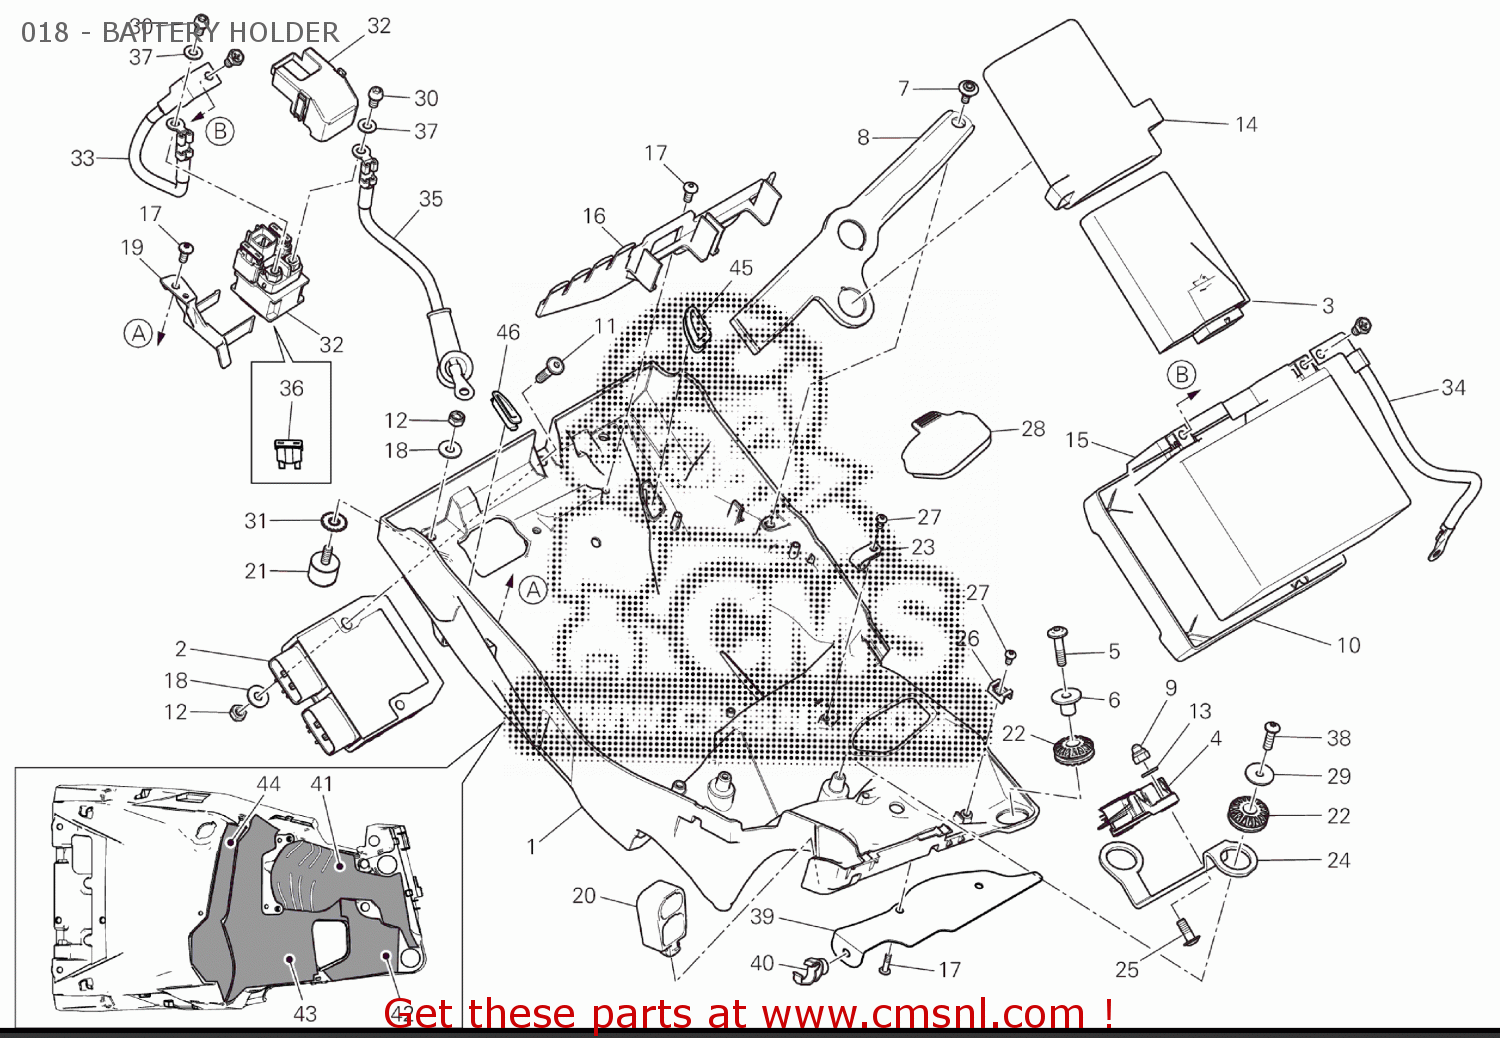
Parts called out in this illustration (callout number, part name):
1	BATTERY HOLDER
2	VOLTAGE REGULATOR
3	BLACKBOX UNIT
4	PIATTAFORMA INERZIALE
5	SCREW
6	SPACER
7	SCREW TCEI M5X9
8	BRACKET, BATTERY BAND
9	NUT, SELF-LOCKING M6
10	BATTERY CARPET
11	SCREW TBEIF M6X25
12	NUT
13	WASHER 6.4X12.5X1.6
14	BRACKET
15	BATTERY
16	BRACKET, FUSE BOX
17	SCREW
18	WASHER 6.4X16X1.5
19	BRACKET, RELAY
20	BRACKET, CONNECTOR
21	VIBRATION DAMPER
22	VIBRATION DAMPER PAD
23	FAIRLEAD
24	BRACKET
25	SCREW
26	HOSE GUIDE
27	SCREW, TAPPING 4X8 WN1412
28	GUARD
29	WASHER 5.3X15X1
30	SCREW TCEIF M6X10
31	TOOTHED LOCK WASHER
32	STARTER RELAY
33	BATTERY - SOLENOID STARTER CABLE
34	BATTERY - ENGINE GROUNDING CABLE
35	SOLENOID STARTER - STARTER MOTOR CABLE
36	FUSE 30A
37	WASHER, SPRING
38	SCREW, TAPPING
39	BATTERY MOUNT HEAT GUARD
40	FAIRLEAD
41	BATTERY MOUNT HEAT GUARD
42	BATTERY MOUNT HEAT GUARD
43	BATTERY MOUNT HEAT GUARD
44	BATTERY MOUNT HEAT GUARD
45	PLUG
46	PLUG, RH
